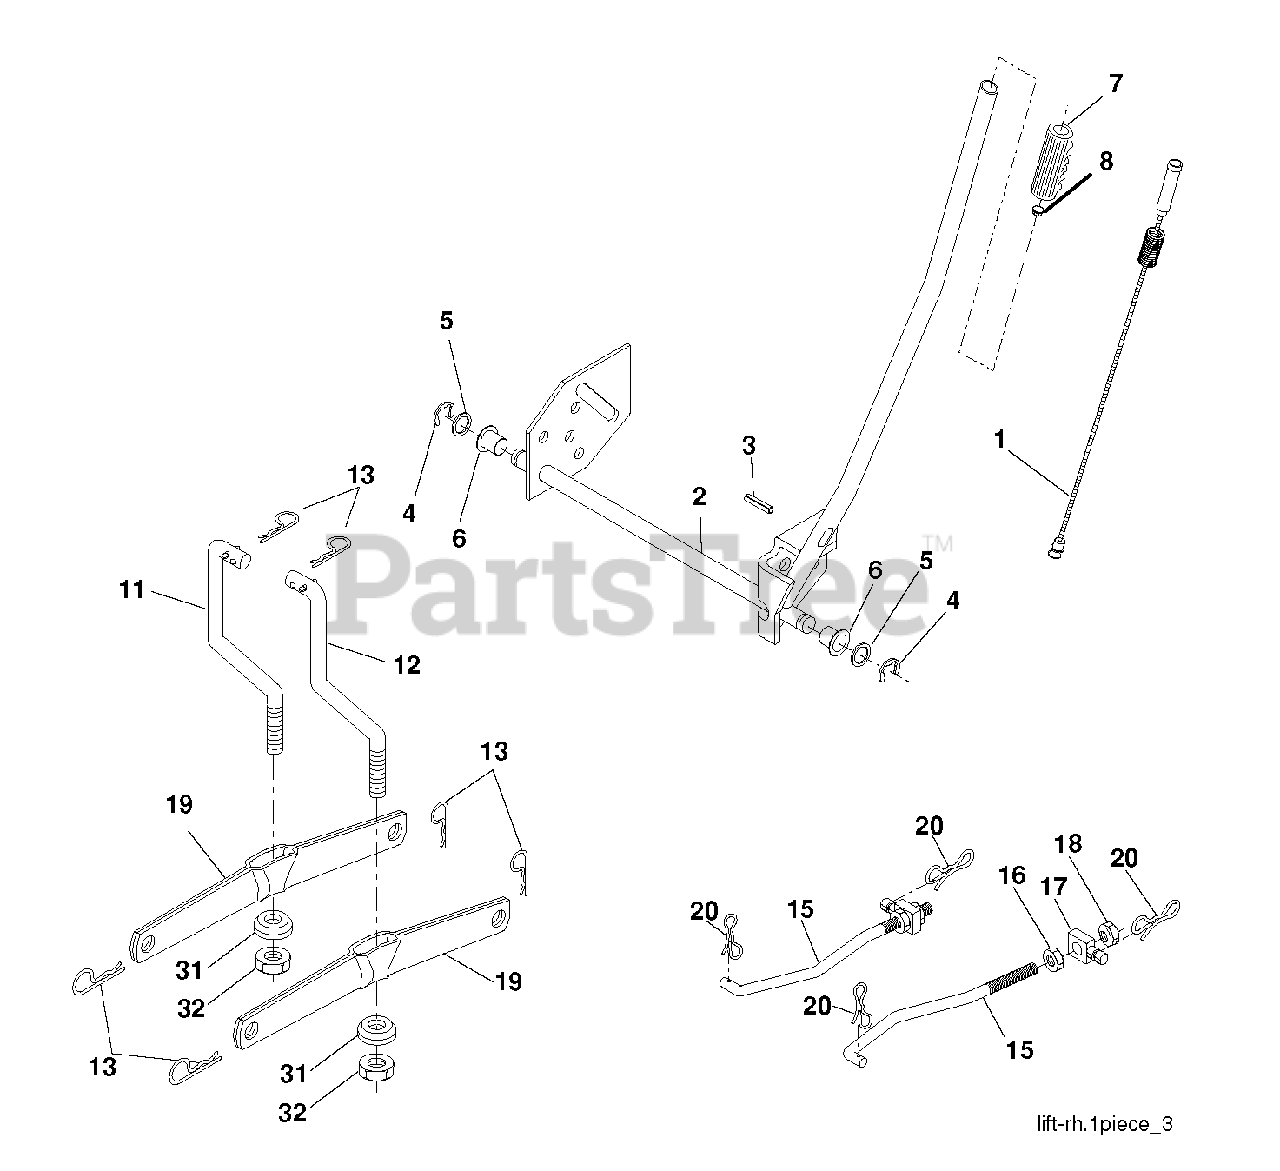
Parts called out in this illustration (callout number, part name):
1	PLUNGER.ASM.LIFT.LVR.BLK.17.32
2	SHAFT ASM R HANDLE
3	PIN GROOVE.
4	RETAINING RING LT
6	BEARING.NYLON
7	GRIP HANDLE
8	PLUNGER BUT KIT
11	LINK LIFT LH
12	Lift Link Assembly, RH
13	RETAINER-SPRNG RB
15	LINK.SUSPENSION.FRONT
16	NUT.HEX.JAM.1/2-13
17	TRUNNION
18	NUT.LK.W/WSH.1/2.
19	ARM.REAR.SUSPENSION
20	PIN.COTTER.7/16.BOW TI.
31	BEARING.PIVOT.LIFT
32	NUT CROWNLOCK 3/8-24
